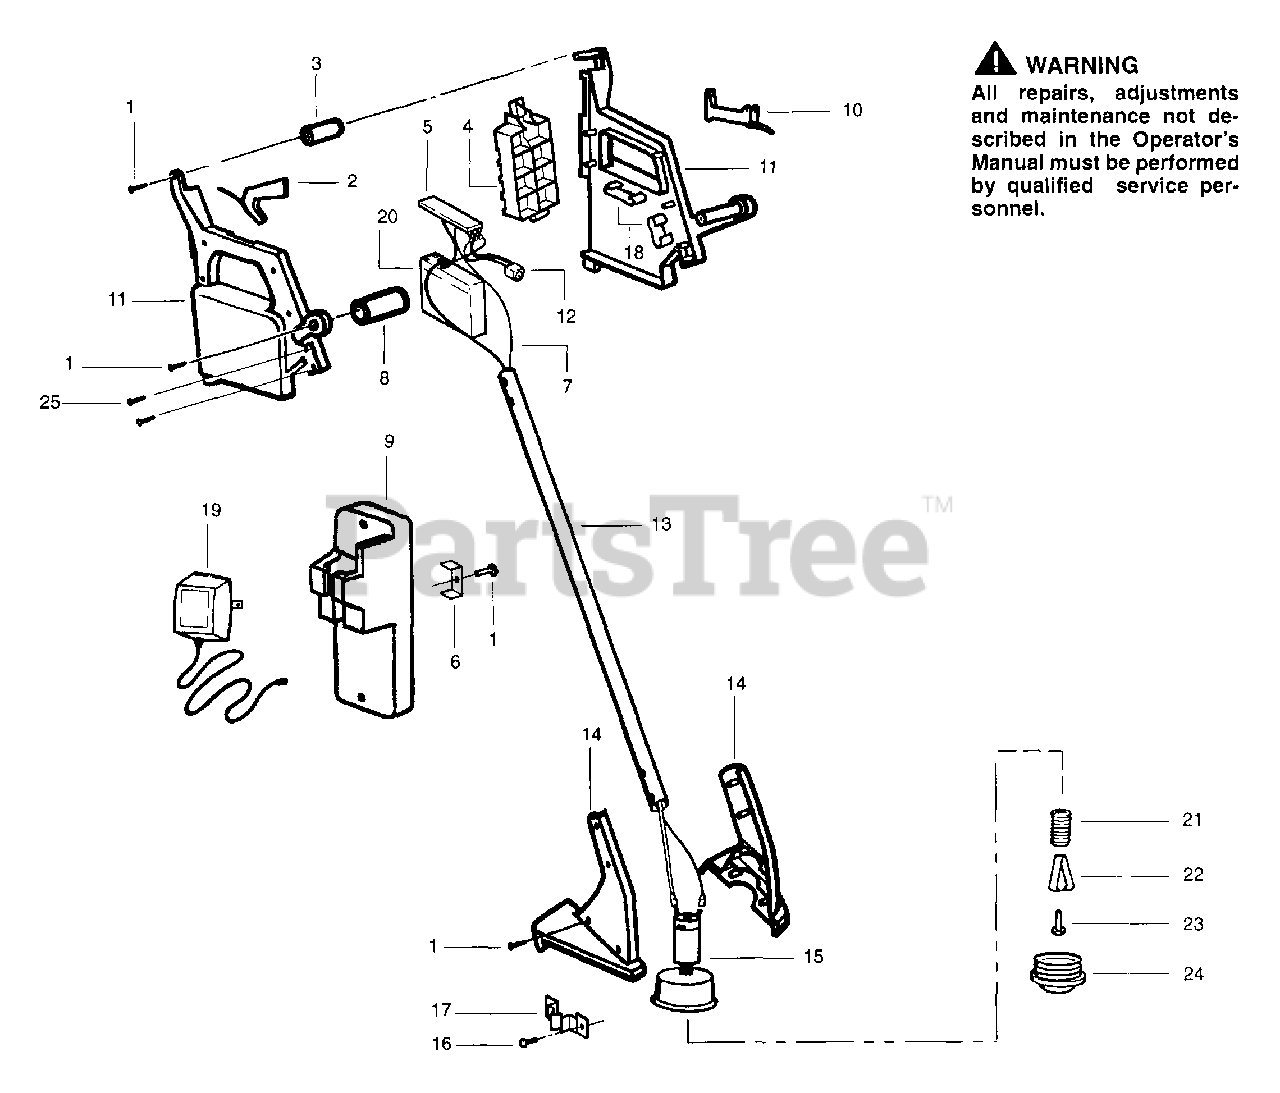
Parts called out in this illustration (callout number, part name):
2	Trigger Lock
3	Wrist Support Cushion
4	Battery Door
5	Circuit Board Ass'y.
6	Probe-Clamp
7	Wire Ass'y. (Red)
8	Assist Handle Cushion
9	Hanging Bracket
10	Trigger Switch
11	Battery Hsg. Set
12	Receptacle Ass'y.
13	Tube w/ Warning Decal
14	Motor Hsg Set w/ Line Limiter
15	Motor/Hub Ass'y.
17	Clamp-Motor
18	Battery Spring
19	Charger
20	Battery Kit
22	Clip Retainer
23	Screw w/Washer
24	Spool w/Line
